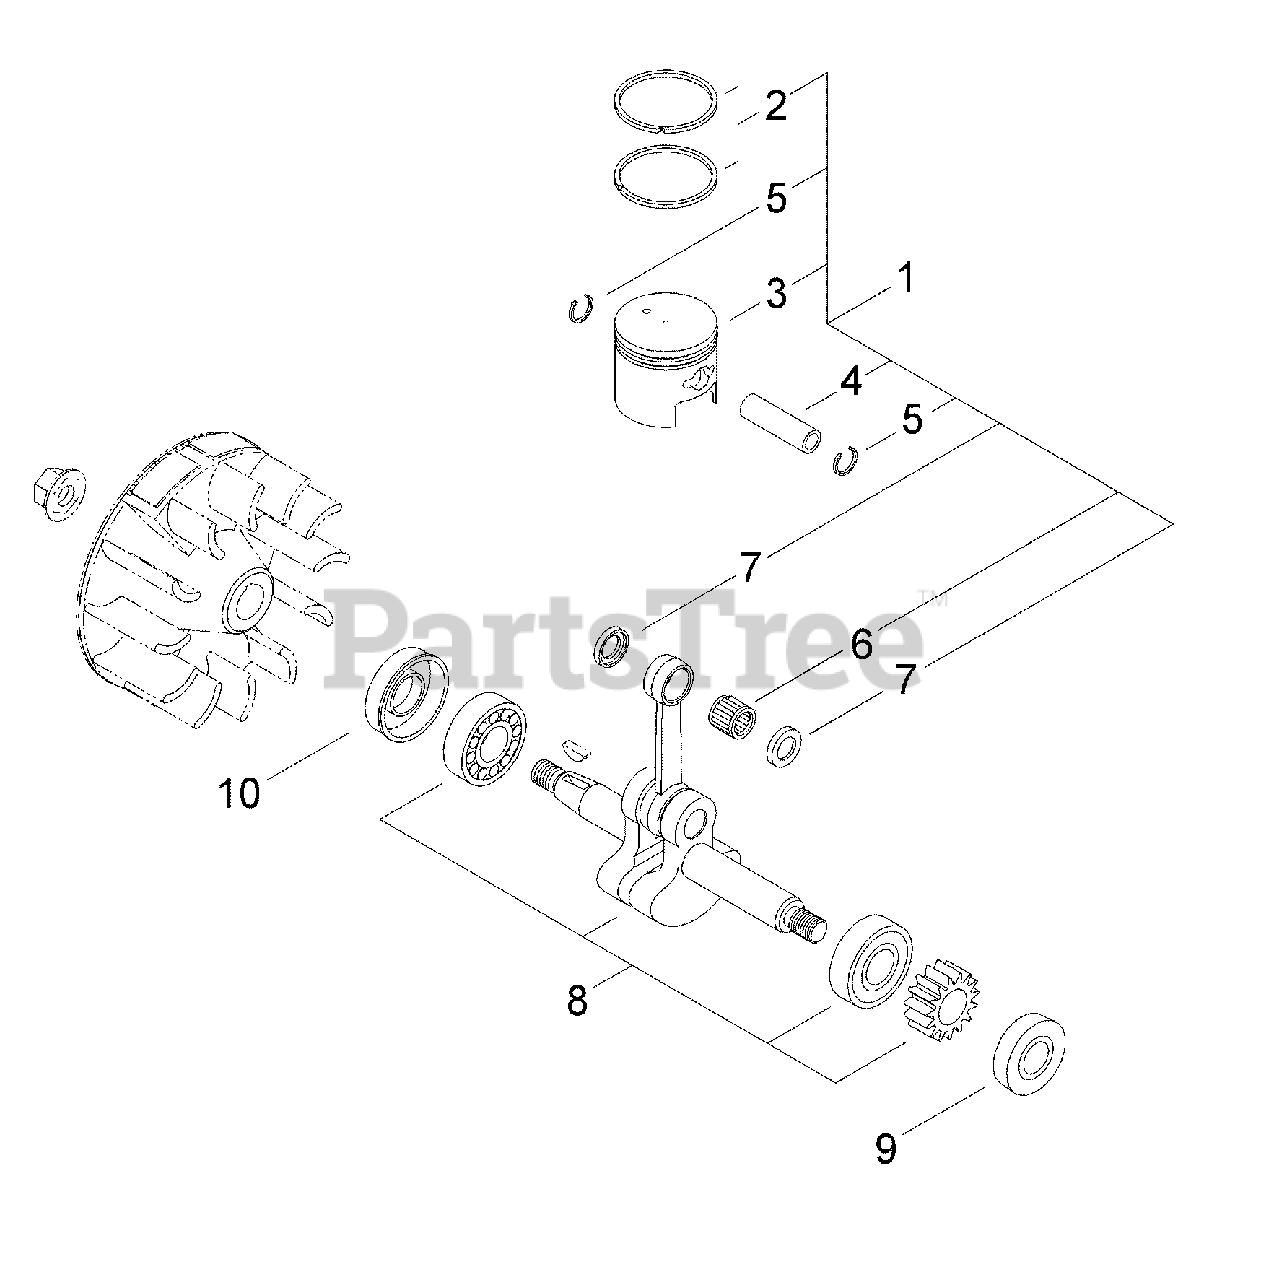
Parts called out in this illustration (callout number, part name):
1	PISTON KIT
2	RING, PISTON
3	PISTON
4	PIN, PISTON 10
5	RING, SNAP
6	BEARING, NEEDLE 10
7	WASHER, THRUST 10
8	CRANKSHAFT ASSY
9	SEAL, OIL 12
10	SEAL, OIL 12
